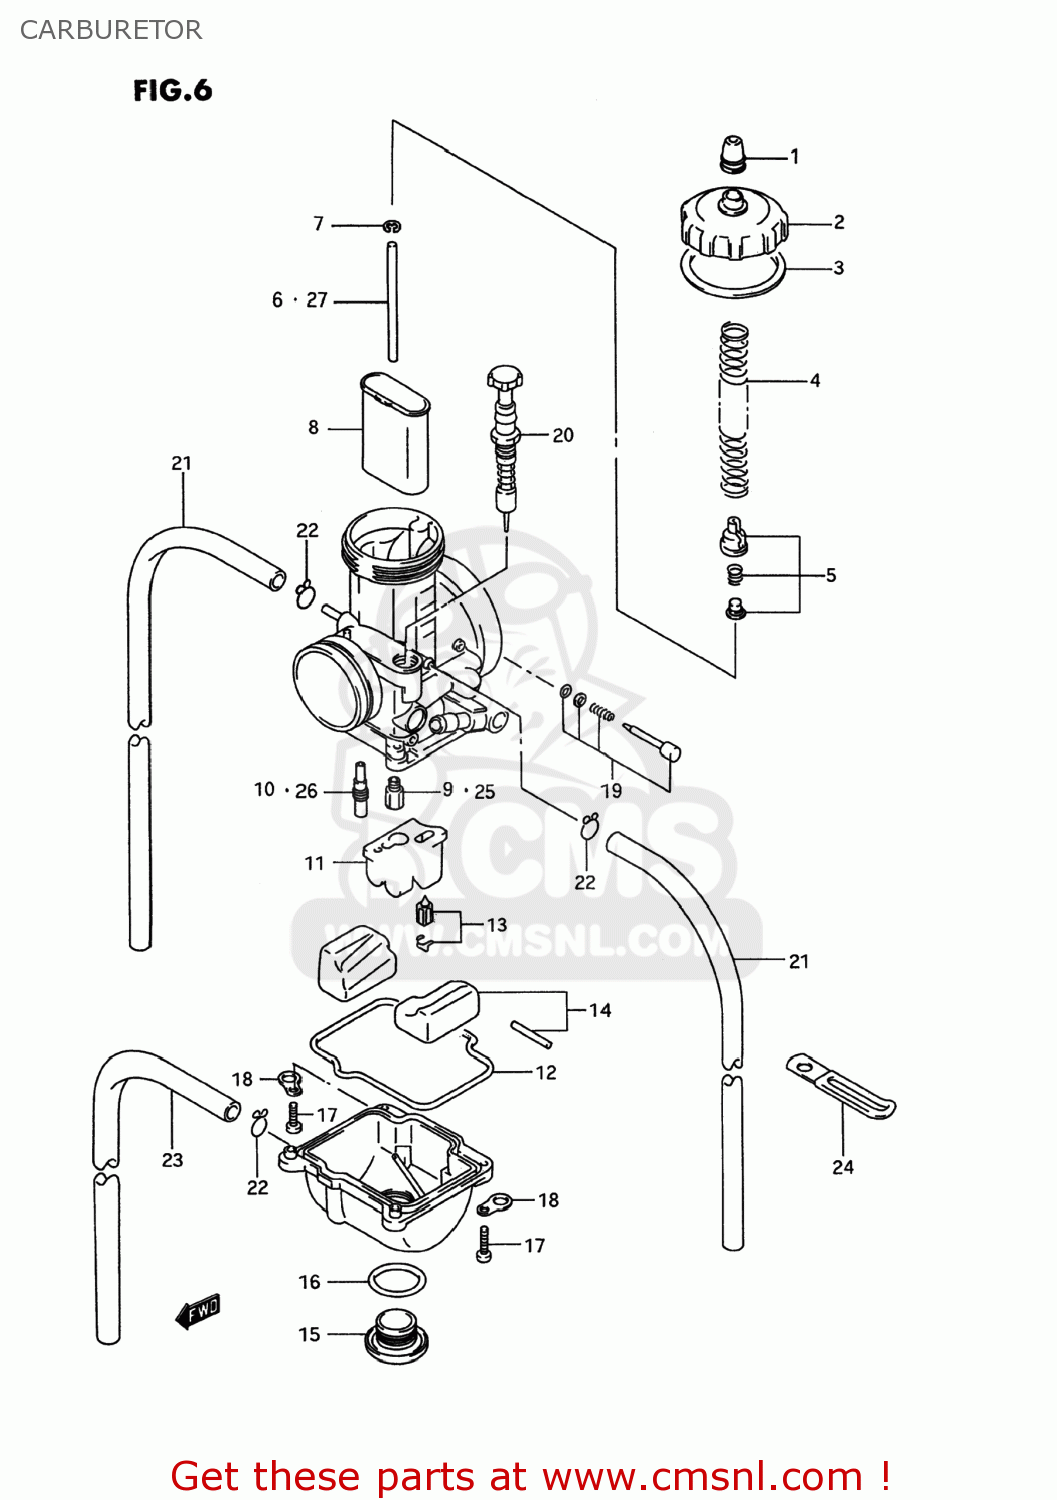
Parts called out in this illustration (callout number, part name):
1	CAP,CARBURETOR
2	CAP,TOP
3	GASKET,TOP CAP
4	SPRING
5	HOLDER SET,CABLE
6	NEEDLE(R1471NS)
7	CLIP,NEEDLE
8	VALVE,PISTON
9	JET,MAIN(200)
10	JET,SLOW(52)
11	HOLDER
12	GASKET,FLOAT CHAMBER
13	VALVE SET,FLOAT
14	FLOAT SET
15	BOLT,DRAIN
16	O RING
17	SCREW
18	PLATE
19	SCREW SET,AIR
20	PLUNGER ASSY
21	HOSE (4X7X440)
22	CLIP
23	HOSE(3.5X6.5X600)
24	CLAMP
25	JET,MAIN(170)
26	JET,SLOW(35)
27	NEEDLE(R1469MS)
